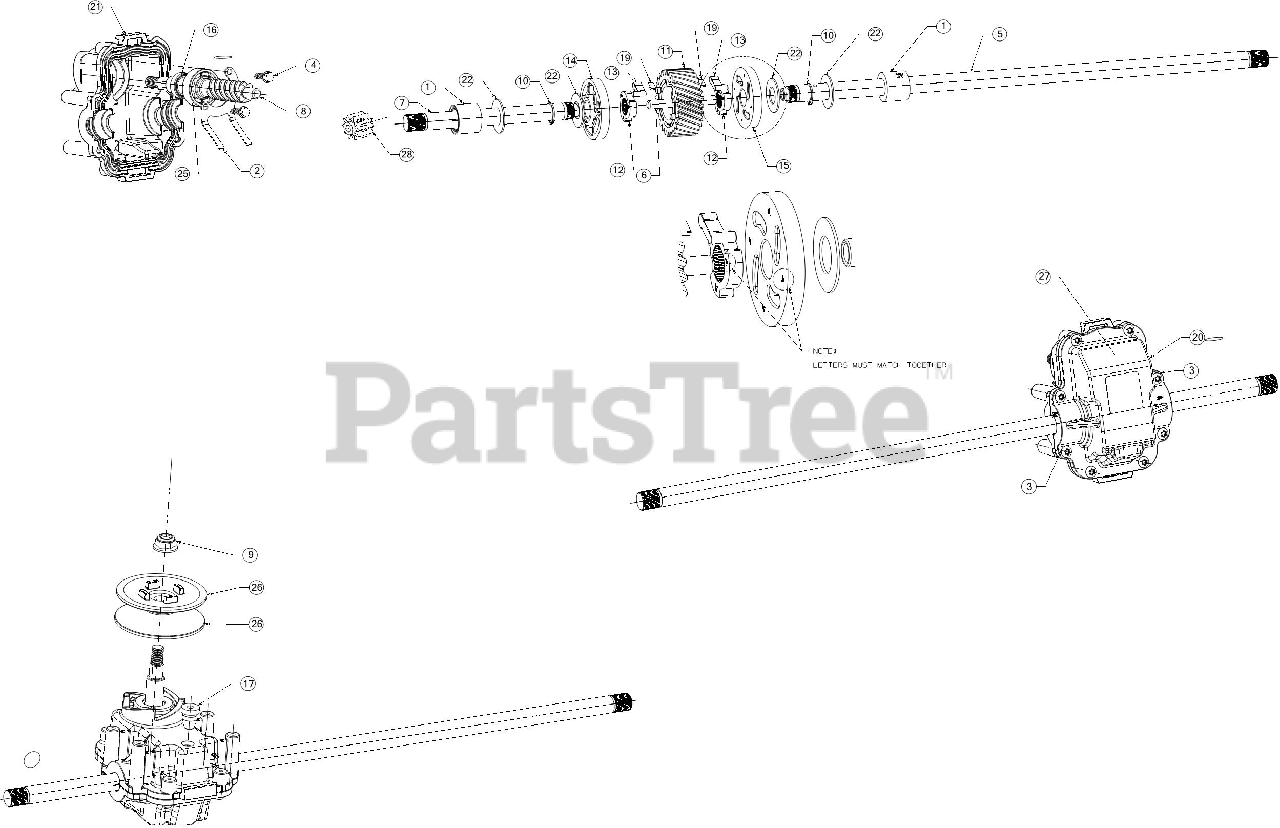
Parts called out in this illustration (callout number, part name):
1	OIL SEAL
3	SCREW .159 X .610
4	SCREW .159 X .43
9	FLANGE LOCK NUT 5/16-18
10	SNAP RING FOR .500
16	OIL SEAL
22	FLAT WASHER .508X1.000X.040
25	BALL BEARING
26	HALF PULLEY 2.5 OD
27	GEAR-SPUR 10T
28	COVER-TRANS RWD SINGLE SPEED
